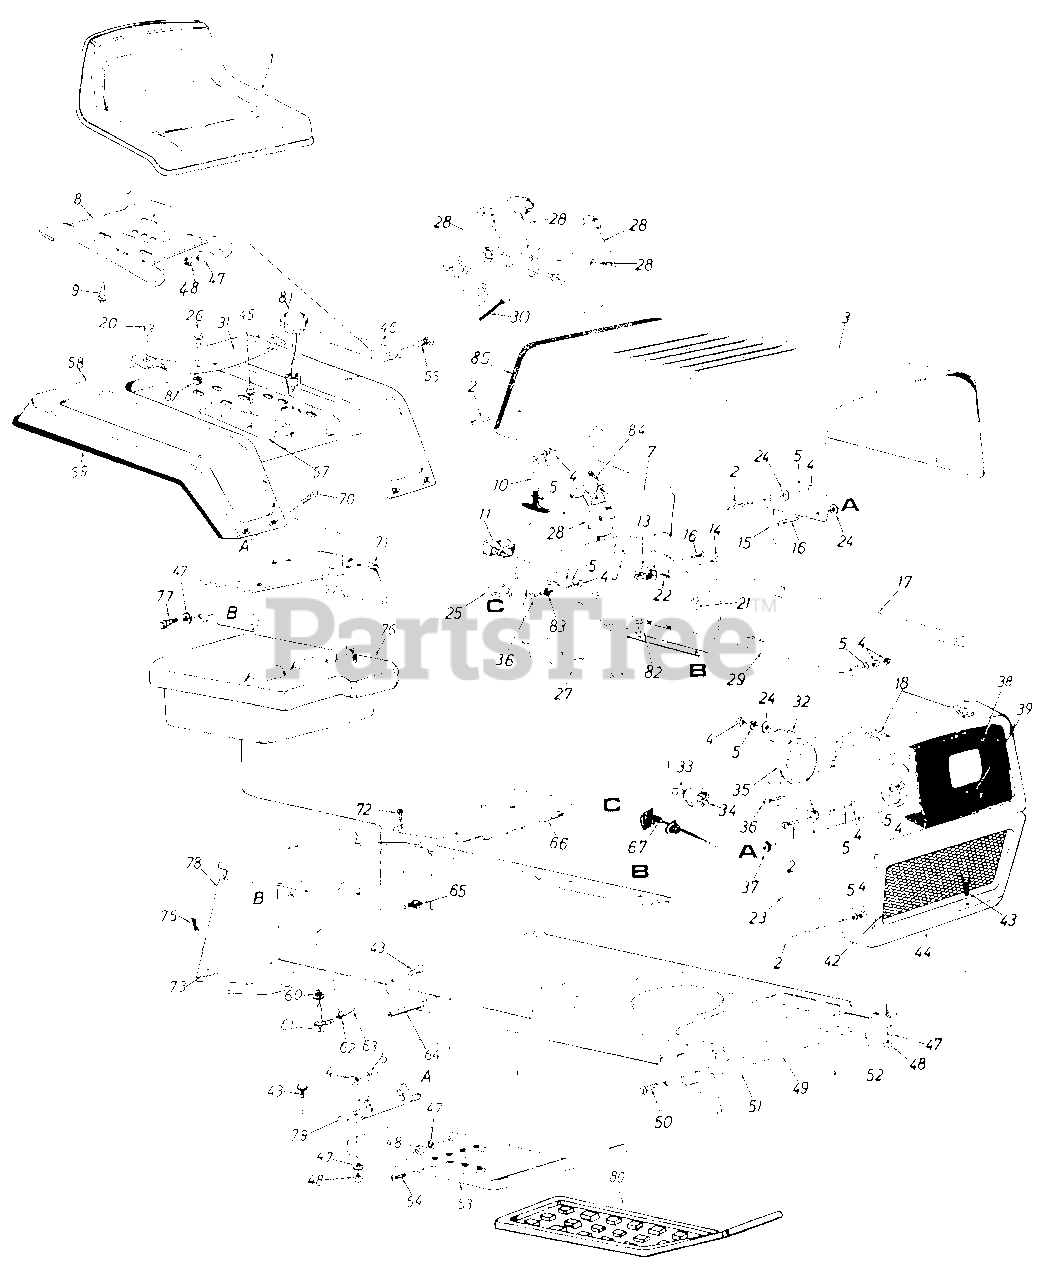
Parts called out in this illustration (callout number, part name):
1	Seat Assembly
2	Truss Mach. Scr. 1/4-20 x .50" Lg.
5	L-Wash. 1/4" Scr.
7	Vinyl Molding Strip-29"
8	Seat Pivot Bracket
9	Hex Wash. AD 0 AB-Tap Scr. 3/8 x 75" Lg.
10	Hood Latch Ass'y.
11	Ammeter
13	Circuit Breaker 8 Amp.
14	Hex Tap Scr. #10 x .50" Lg.
16	Truss Mach. Scr. 1/4-20 x .75" Lg.
17	Grille Positioning Rod
18	PVC Foam Strip 1/2 x 1.00" x 2.00" Lg.
20	Grommet
21	Hex Thd. Rolling Scr. 1/4" x .50" Lg.
22	Speed Nut #10Z
23	Grille Side Panel-R.H.
24	Fl-Wash. 1/4" I.D.
25	Light Switch
26	Hex Wash. Hd. Self-Tap Scr. 5/16-18 x 1.25" Lg.
27	Dash Panel Ass'y.
28	Throttle Control Box Comp.
29	Grille Positioning Rod
30	Throttle Control Wire
31	Seat Spring
32	Head Lamp Retainer
33	Ignition Key
34	Ignition Switch
35	Head Lamp
36	Truss Machine Scr. 1/4-20 x .75" Lg.
37	Rubber Wash. .50" I.D. x 1.00 O.D. x .25 Thk.
38	Headlight Bezel
39	Hex Wash. Hd. Scr. #8-32 x .38" Lg.
42	Grille Screen
43	Hex Scr. 5/16-18 x .75" Lg.
44	Grille Ass'y.
45	Hex Wash. Hd. Self-Tap Scr. 5/16-18 x .50 Lg.
46	Seat Brkt.-L.H.
47	L-Wash. 5/16" Scr.
48	Hex Nut 5/16-18 Thd.t
49	Lower Frame Ass'y.
50	Hex Thd. Rolling AB Scr. 5/16 x .75" Lg.
51	Grille Mount Brkt.-R.H.
52	Grille Mount Brkt.-L.H.
53	Running Board-R.H.
54	Truss Mach. Scr. 5/16-18 x .75" Lg.
55	Shld. Bolt .437" Dia. x .162" Lg.
57	Seat Brkt.-R.H.
60	Bushing
61	90ø Nipple
63	Gas Line 46" Lg.
64	Running Board Rod
66	Transmission Cover
67	Choke Control Comp.
70	Carriage Bolt 1/4-20 x 50 Lg
71	Seat Mounting Channel
72	B-Tap Scr. #10 x .50" Lg.
75	Internal Cotter Pin
77	Hex Wash. Hd. AB-Tap Scr. 3/8 x .75" Lg.
78	Hitch Plate
79	Fender Brkt.-R.H.
82	Hex Thd. Rolling Scr. 5/16-24 x .75" Lg.
83	External Wash. 1/4" I.D.
84	Truss. Mach. Scr. #10 x .5" Lg.
85	Trim strip-30" Lg.
87	Spacer
